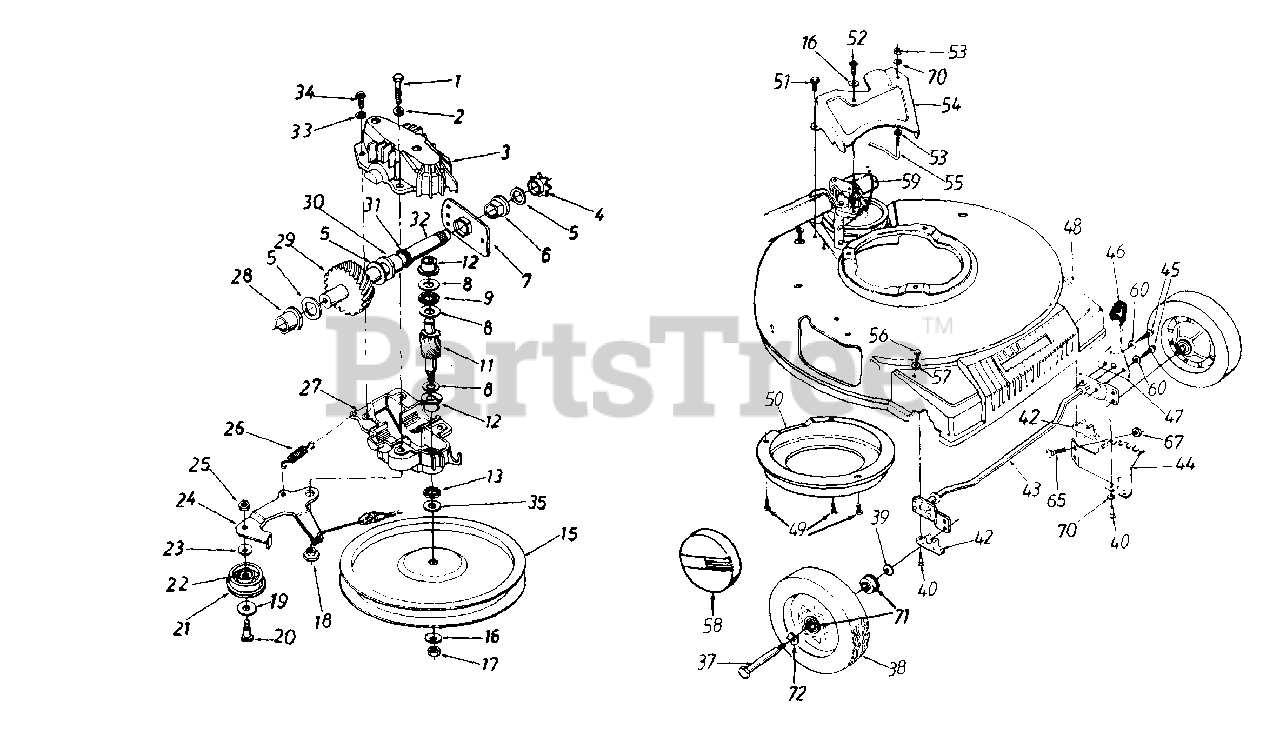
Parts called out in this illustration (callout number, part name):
1	Hex Patch Bolt 1/4-20 x 1.25
2	L-Wash. 1/4" I.D.
3	Upper Hsg. Half
4	#48 Sprocket 7T x 1/2 Pitch
5	Fl-Wash. 5/8" I.D. x .030
6	Hex Flange Brg. .631" I.D.
8	Thrust Wash. .382" I.D. x .70" O.D.
9	Thrust Bearing .375" I.D. x .812" O.D.
11	11 Tooth Pinion Shaft
12	Flange Bearing
15	Fl-Pulley 5.06" O.D.
16	Bell-Wash. .265" I.D. x .75"
17	Hex L-Nut 1/4-28 L.H. Thd.
18	Shld. Spacer .375" Dia. x .170
19	FL-Wash. .390" I.D. x 1.0"
20	Shld. Bolt .375" Dia. x .40"
21	Fl-Idler Plastic 1.50" Dia.
22	Needle Brg. .375" x .31
24	Idler Brk't. Ass'y.
25	Hex Patch L-Nut 1/4-28 Thd.
26	Extension Spring 1.12" Lg.
27	Lower Hsg. Half
28	Flange Bearing .566 Dia.
29	33 Tooth Helical Gear
30	Flange Bearing .629 Dia.
31	Oil Seal .625 Dia.
32	Gear Sprocket Shaft
33	L-Wash. #10 I.D.
34	Hex B-Tap Scr. #10 x .62"
35	Hex Washer .26" x .88"
37	Front Axle Bolt
38	Wheel Ass'y. Comp.
39	Bell-Wash. .380" I.D. x .88
40	Hex Wash. Hd. Scr. 1/4 x 1" Lg.
42	Block Bushing
45	Hex TT-Tap Scr. 1/4-20 x .38"
46	Knob
47	Spring Lever
48	Plastic Front End
49	Hex B-Tap Scr. 1/4" x .38"
52	Hex Wash. Hd. B-Tap Scr. 1/4 x .62" (Spec.)
53	Hex Nut 1/4-20 Thd.
56	Torx Truss Hd. Scr. 5/16 x .75"
57	Bell-Wash. .345" I.D. x .88"
58	Hub Cap
59	S.P. Cable
60	External L-Wash. 1/4" I.D.
65	Carr. Bolt 1/4-20 x .5" Lg.
67	Hex Flange L-Nut 1/4-20 Thd.
70	L-Wash. 1/4" I.D.
71	Wheel Bearing
72	Wave Washer
